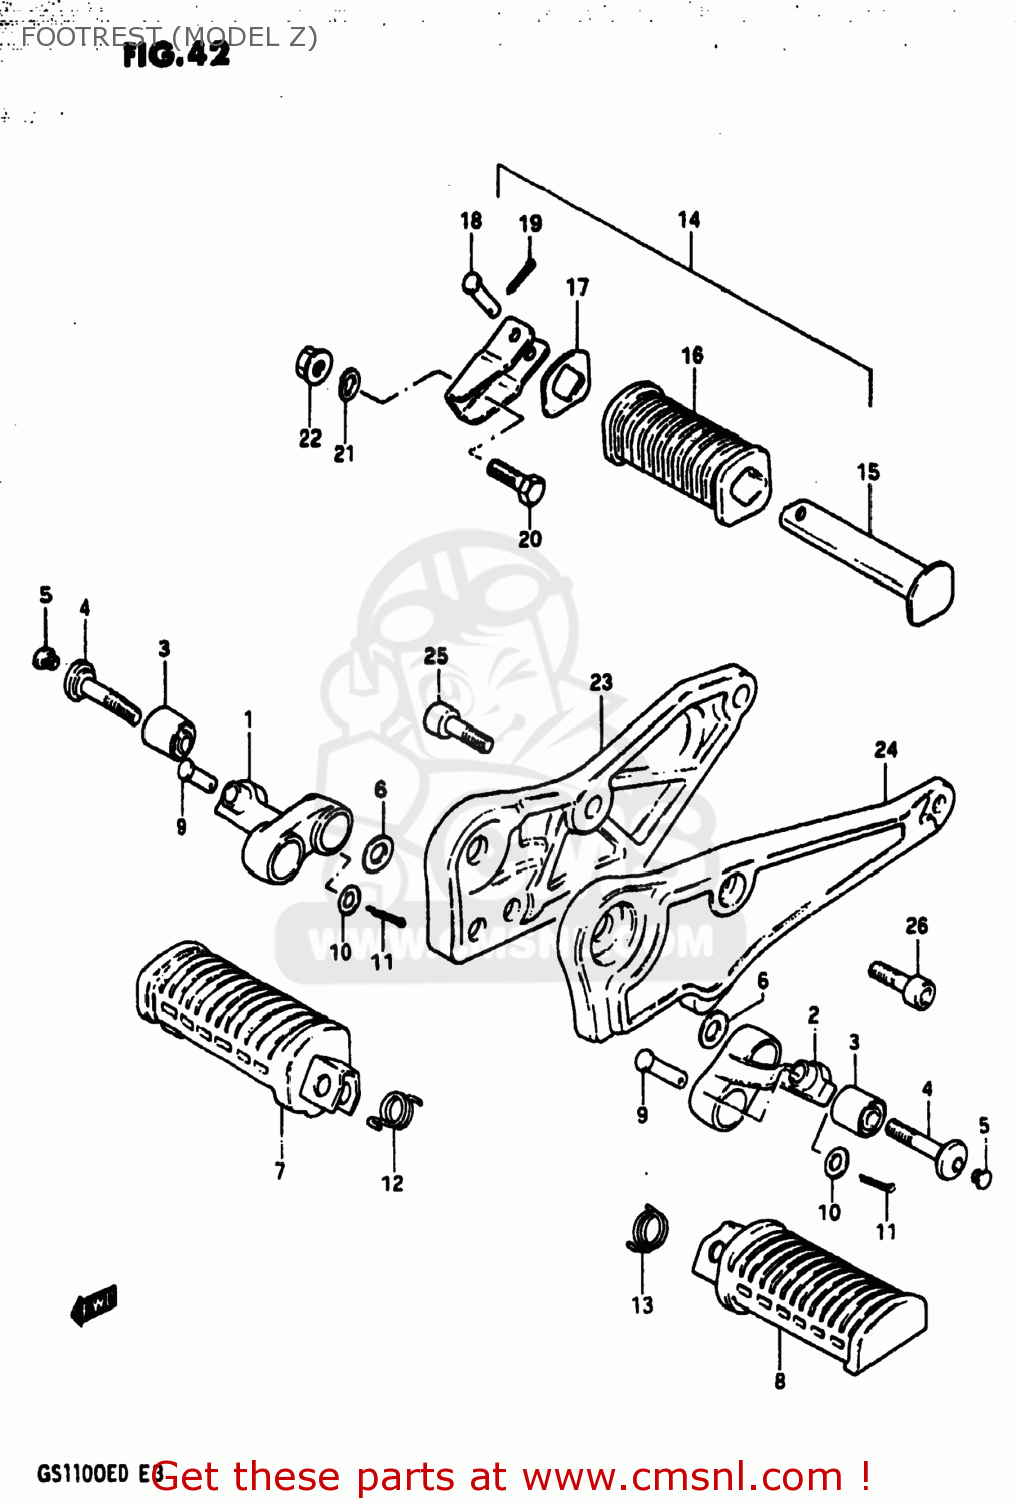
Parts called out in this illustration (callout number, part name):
1	BAR,FRONT FOOTREST,RIGHT
2	BAR,FRONT FOOTREST,LEFT
3	BUSH
4	BOLT(10X50)
5	CAP
6	WASHER
7	RUBBER,FOOTREST
8	FOOTREST
9	PIN
10	WASHER
11	PIN 20X20
12	SPRING
13	SPRING
14	FOOTREST ASSEMBLY,REAR
15	BAR,REAR FOOTREST
16	RUBBER,REAR FOOTREST
17	WASHER,REAR FOOTREST RUBBER
18	PIN
19	PIN 20X20
20	BOLT,M10X1.25X
21	LOCK WASHER
22	NUT
23	BRACKET,MUFFLER,RIGHT
24	BRACKET
25	BOLT
26	BOLT
